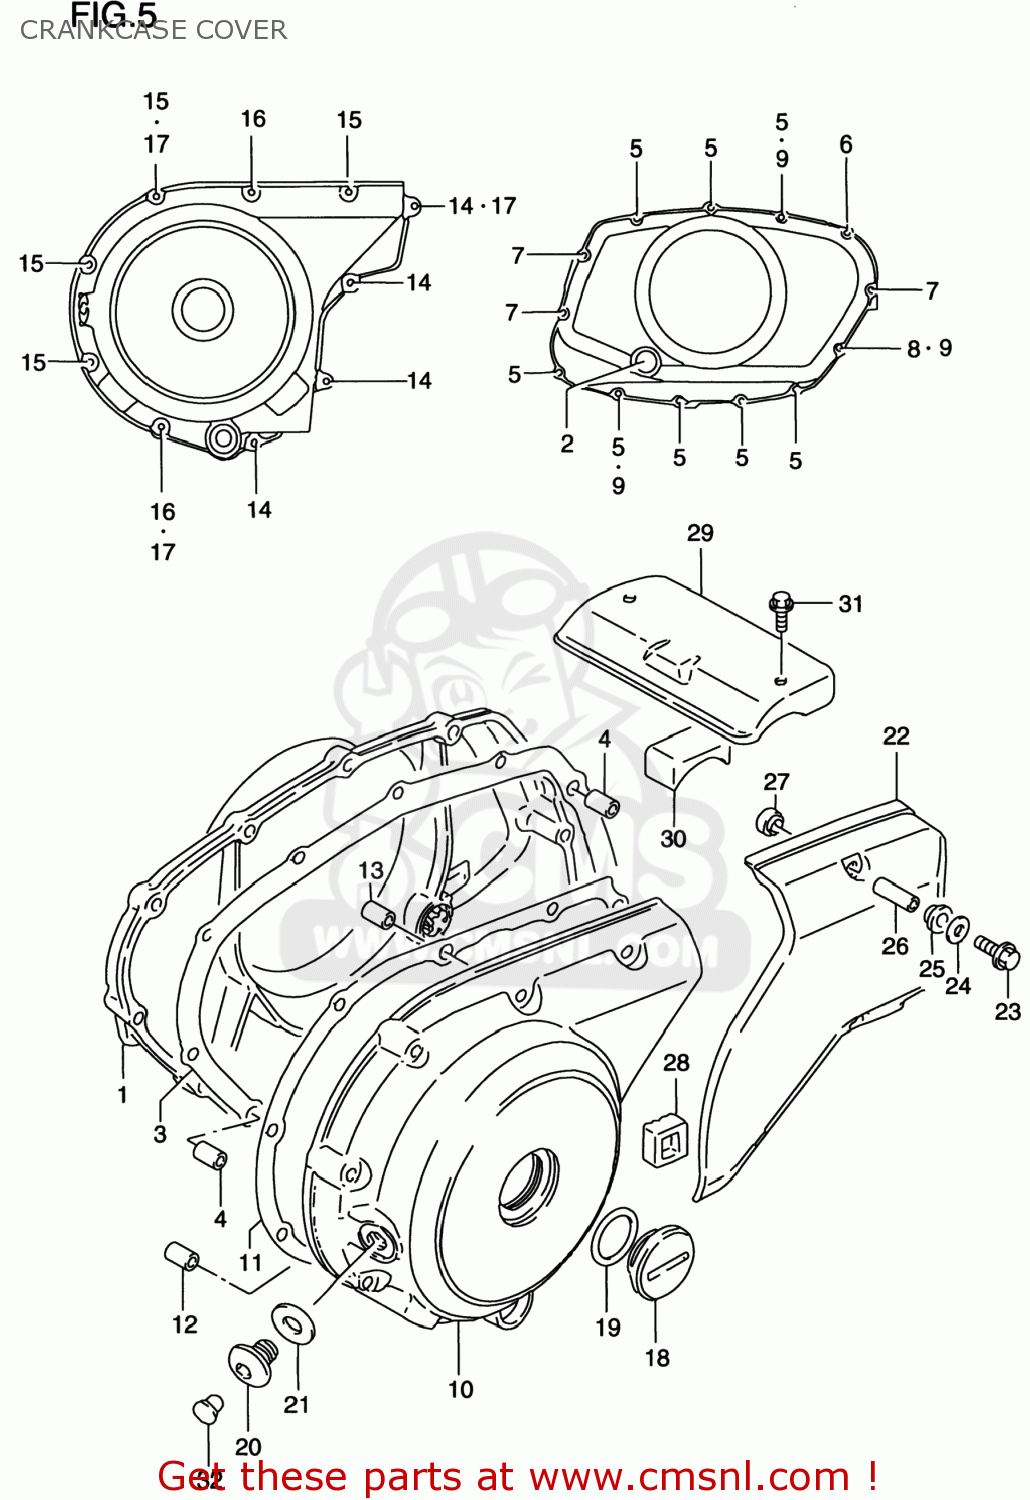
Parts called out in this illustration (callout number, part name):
1	COVER,CLUTCH
2	LENS,OIL LEVEL CHECK
3	GASKET,CLUTCH COVER (NAS)
4	PIN
5	BOLT
6	BOLT
7	BOLT
8	BOLT
9	GASKET(5.8X11X1.2) (NAS)
10	COVER,GENERATOR
11	GASKET,GENERATOR COVER (NAS)
12	PIN(8.4X11X20)
13	PIN
14	BOLT
15	BOLT
16	BOLT
17	GASKET(5.8X11X1.2) (NAS)
18	Chrome Crankshaft Plug
19	O RING(D:3.1,ID:32.7)
20	PLUG,14X12
21	GASKET(13.8X18.8X4.8) (NAS)
22	COVER,SECONDARY GEAR CASE
23	BOLT
24	WASHER(6.5X14X1.6)
25	WASHER(8.7X15X2.1)
26	SPACER(6.5X9X33.3)
27	WASHER(8.7X16X5)
28	DAMPER,SECONDARY COVER
29	COVER,STARTER MOTOR
30	DAMPER,MOTOR COVER
31	BOLT
32	CAP(OD:12)
